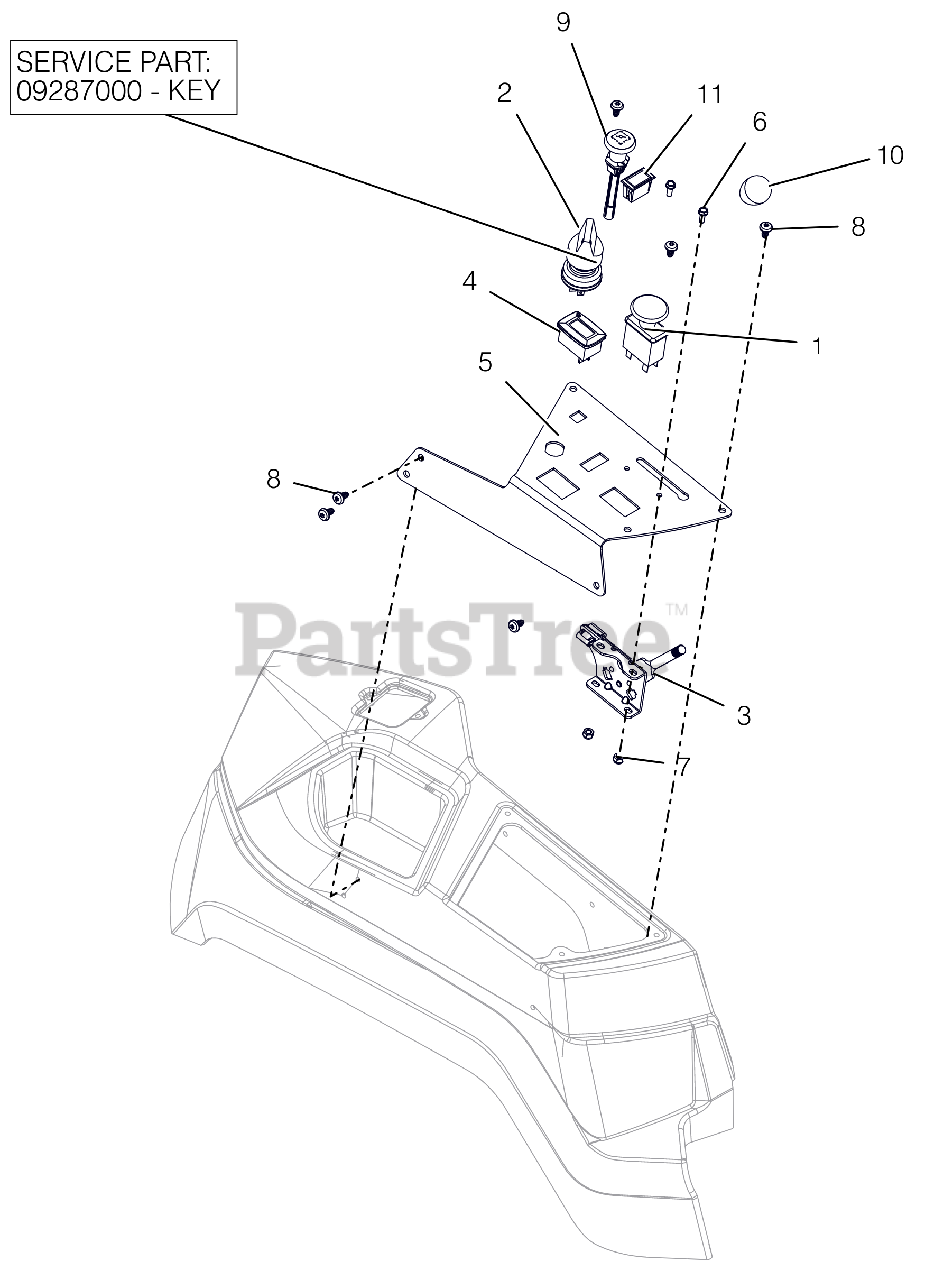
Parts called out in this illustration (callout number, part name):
1	SWITCH, CLUTCH
2	SWITCH, IGNITION
2	KEY, W/ SHIELD
3	CABLE, PRO THROTTLE CONTROL
4	METER, HOUR W/MAINTENANCE
5	PLATE, APEX CONTROL PANEL
6	@SCR-MCH 10-24X.50 HWH YWZC
7	@NUT-LK-NYL 10-24 W/INSRT YWZC
8	SCR-PAN .25-15X.50 6L H/LZB500
9	CABLE - CHOKE, SNAP-IN
10	KNOB-CONTROL-BLACK .38-16X.50
11	SWITCH,BLANK
